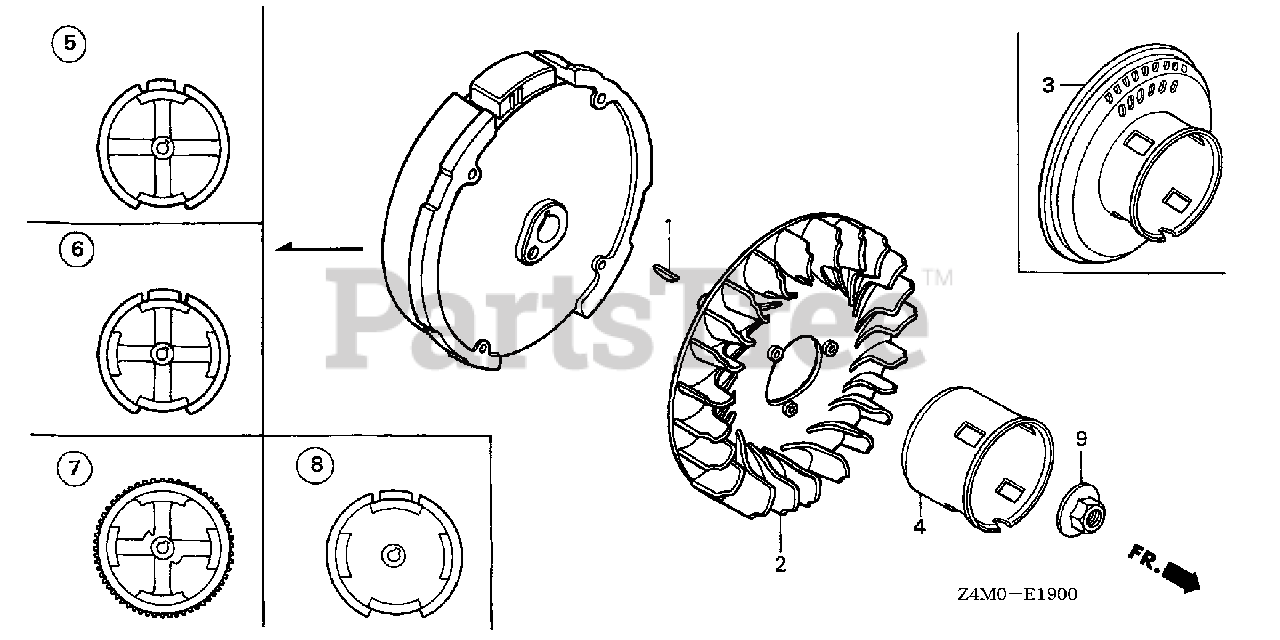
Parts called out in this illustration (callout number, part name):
1	KEY, SPECIAL WOODRUFF (25X18)
2	FAN, COOLING
3	PULLEY, STARTER
5	FLYWHEEL
9	NUT, SPECIAL (14MM)
